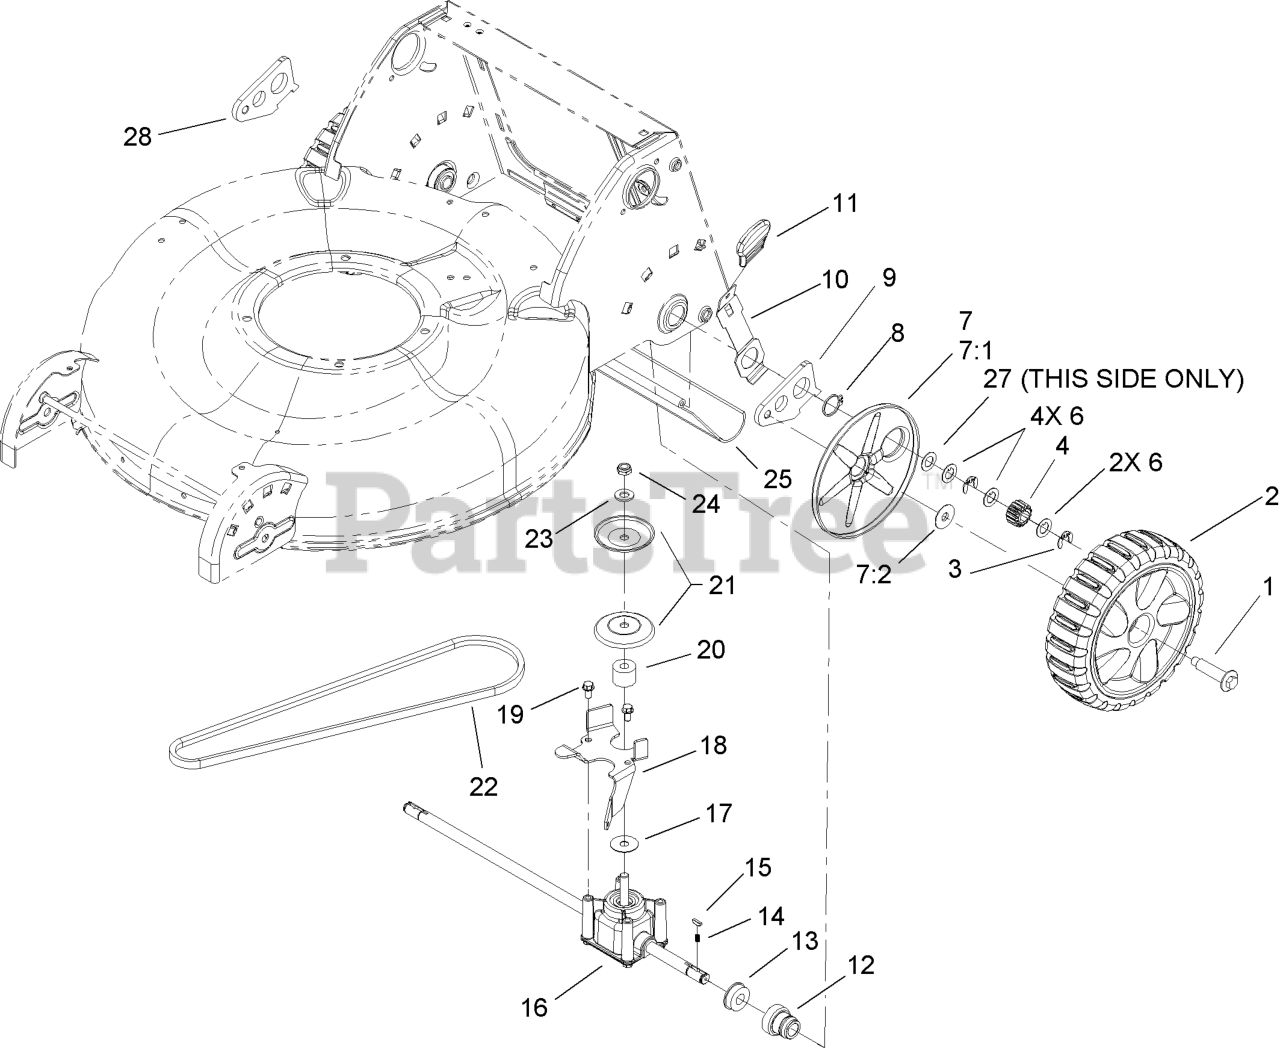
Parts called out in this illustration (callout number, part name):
1	BOLT-SHOULDER
2	REAR WHEEL ASM
3	KLIPRING-LOCKING
4	Gear-Pinion, 15t
6	Washer-Thrust
7	WHEEL COVER ASM
7:1	COVER-WHEEL
7:2	WASHER-STEPPED
8	RING-RETAINING
9	ARM-REAR PIVOT, LH
10	ARM-SPRING, REAR
11	KNOB-LEVER, HOC
12	RETAINER-BEARING, HOC
13	BEARING-BALL
14	SPRING-COMPRESSION
16	TRANSMISSION ASM
17	Washer-Shield
18	BRACKET-TRANSMISSION
19	SCREW-HWH
21	PULLEY-HALF
23	WASHER-FLAT
24	NUT-LOCK
25	SHIELD-TRAILING
28	ARM-REAR PIVOT, RH
